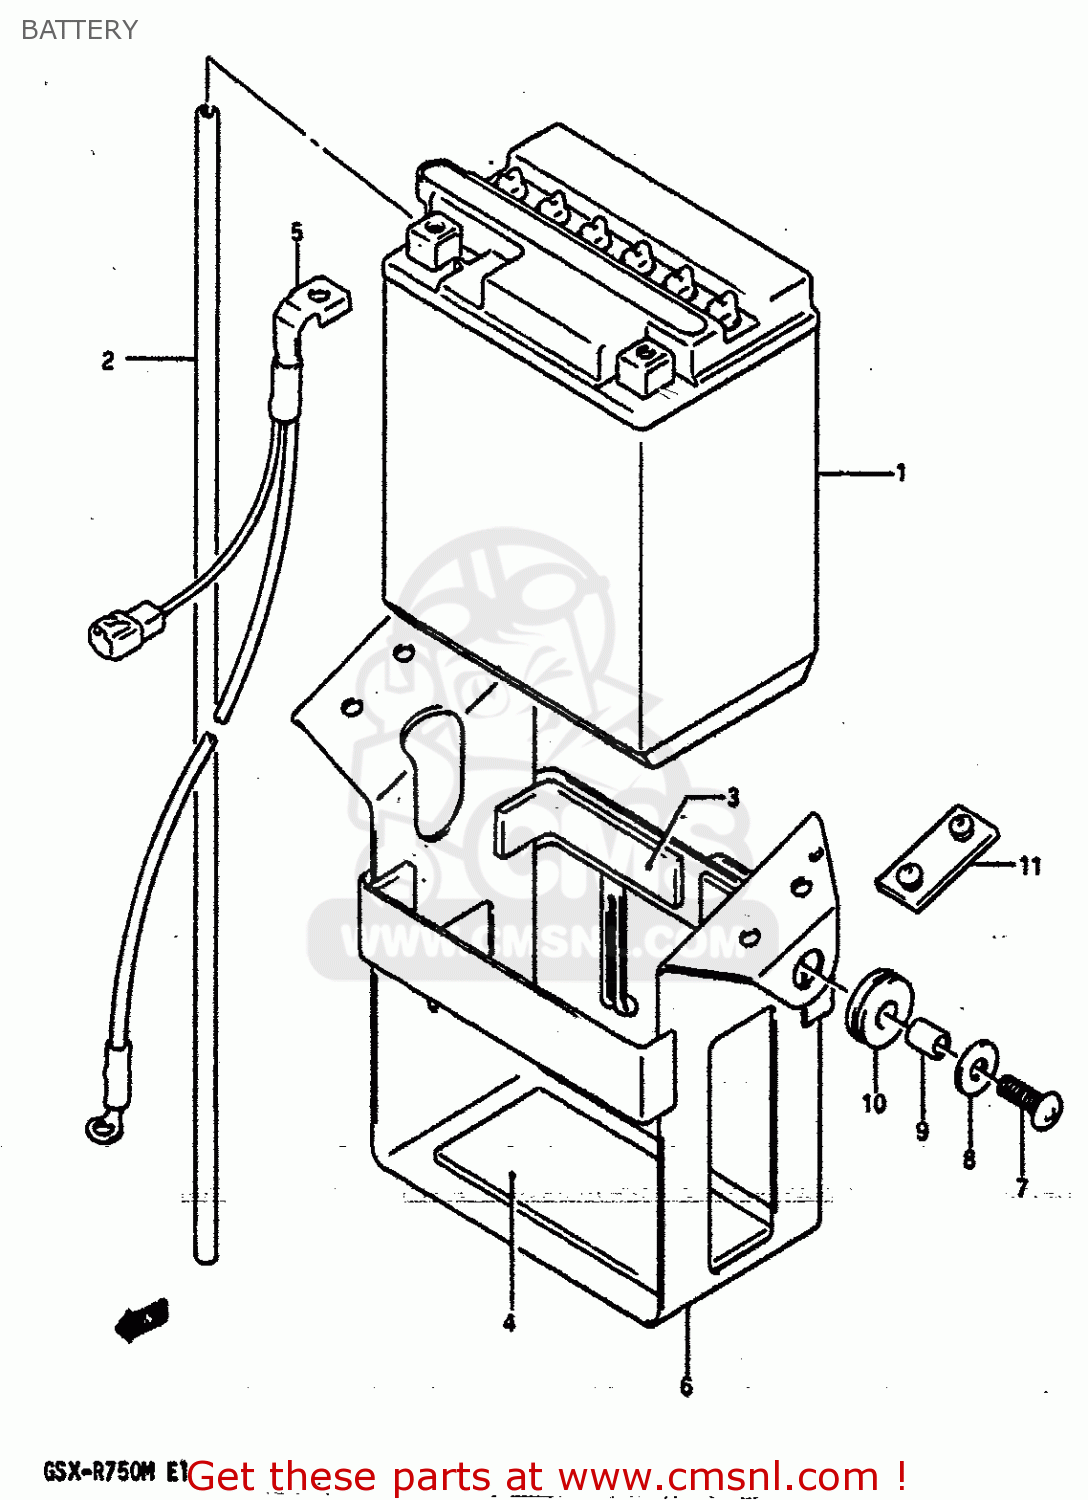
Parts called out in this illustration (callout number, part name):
1	BATTERY ASSY (12V)
2	HOSE,BATTERY EXHAUST
3	PROTECTOR,20X9
4	PROTECTOR(170X95X3.0)
5	WIRE,BATTERY MINUS LEAD
6	HOLDER COMP,BATTERY
7	SCREW
8	WASHER
9	SPACER
10	CUSHION
11	CUSHION
